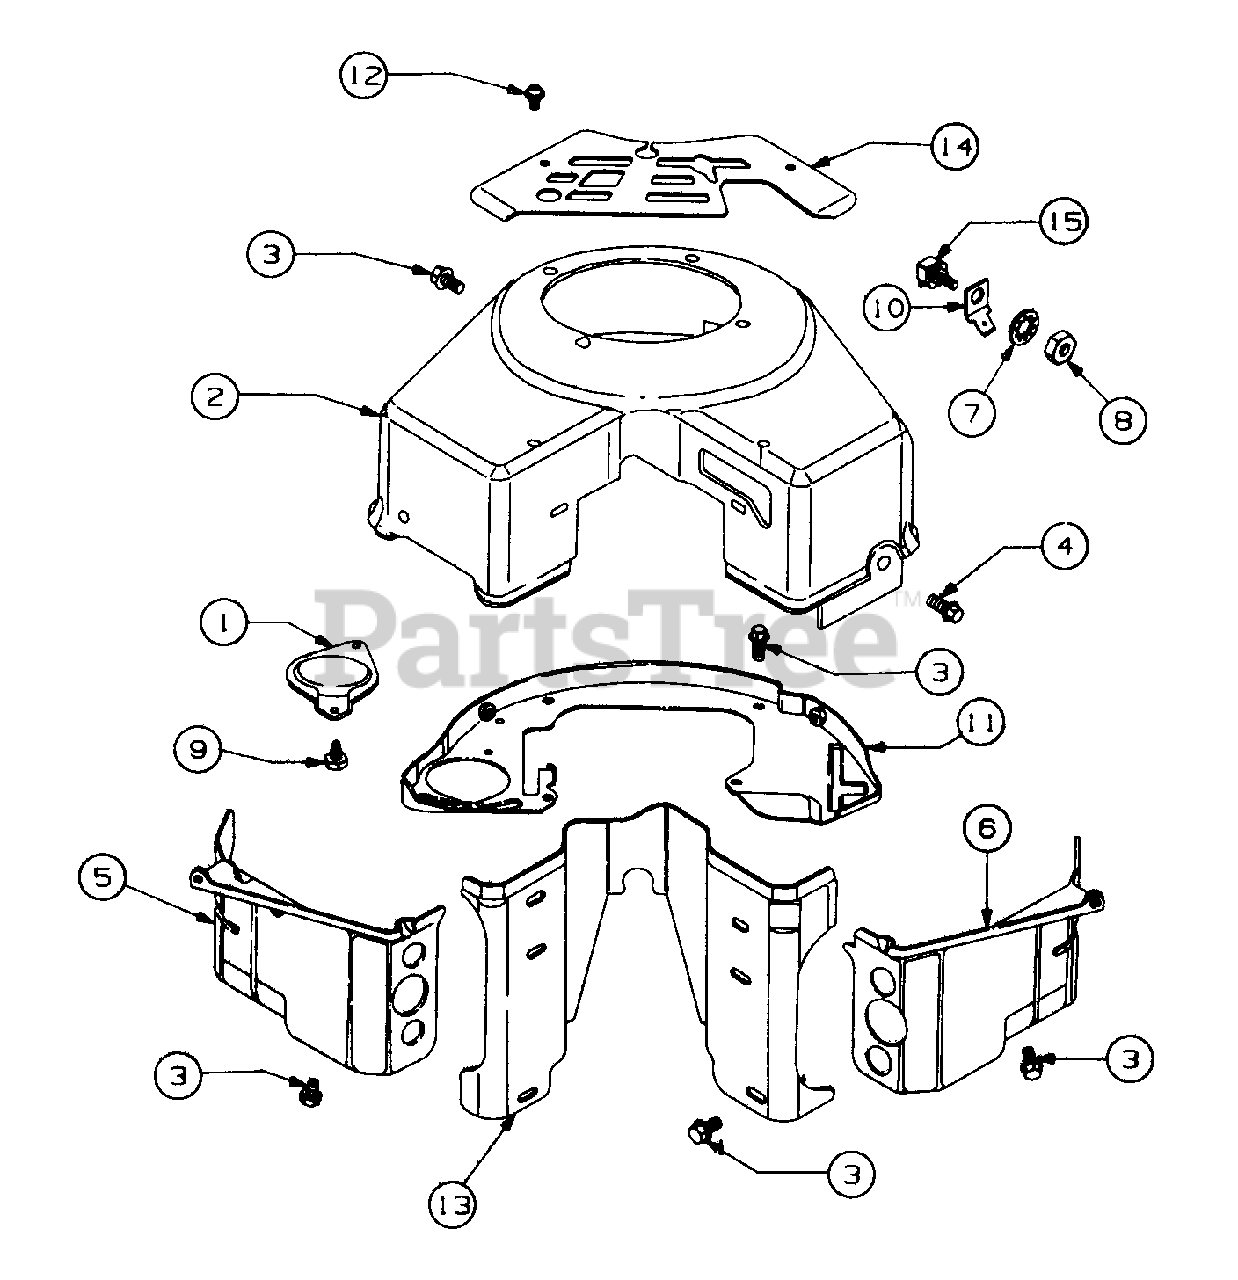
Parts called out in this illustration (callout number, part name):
1	Cover, Starter (Black)
2	Housing, Blower
3	Screw, Sem
4	Screw, Sem
5	Cover, Air Guide (Cylinder #1 Black)
6	Cover, Air Guide (Cylinder #2 Black)
7	Washer, Lock
9	Screw, Sem
10	Terminal, Spade
11	Back Plate Assy (Black)
12	Screw, Sem
13	Valley Cover, Air Guide (Black)
14	Cover, Carburetor
15	Insulator
